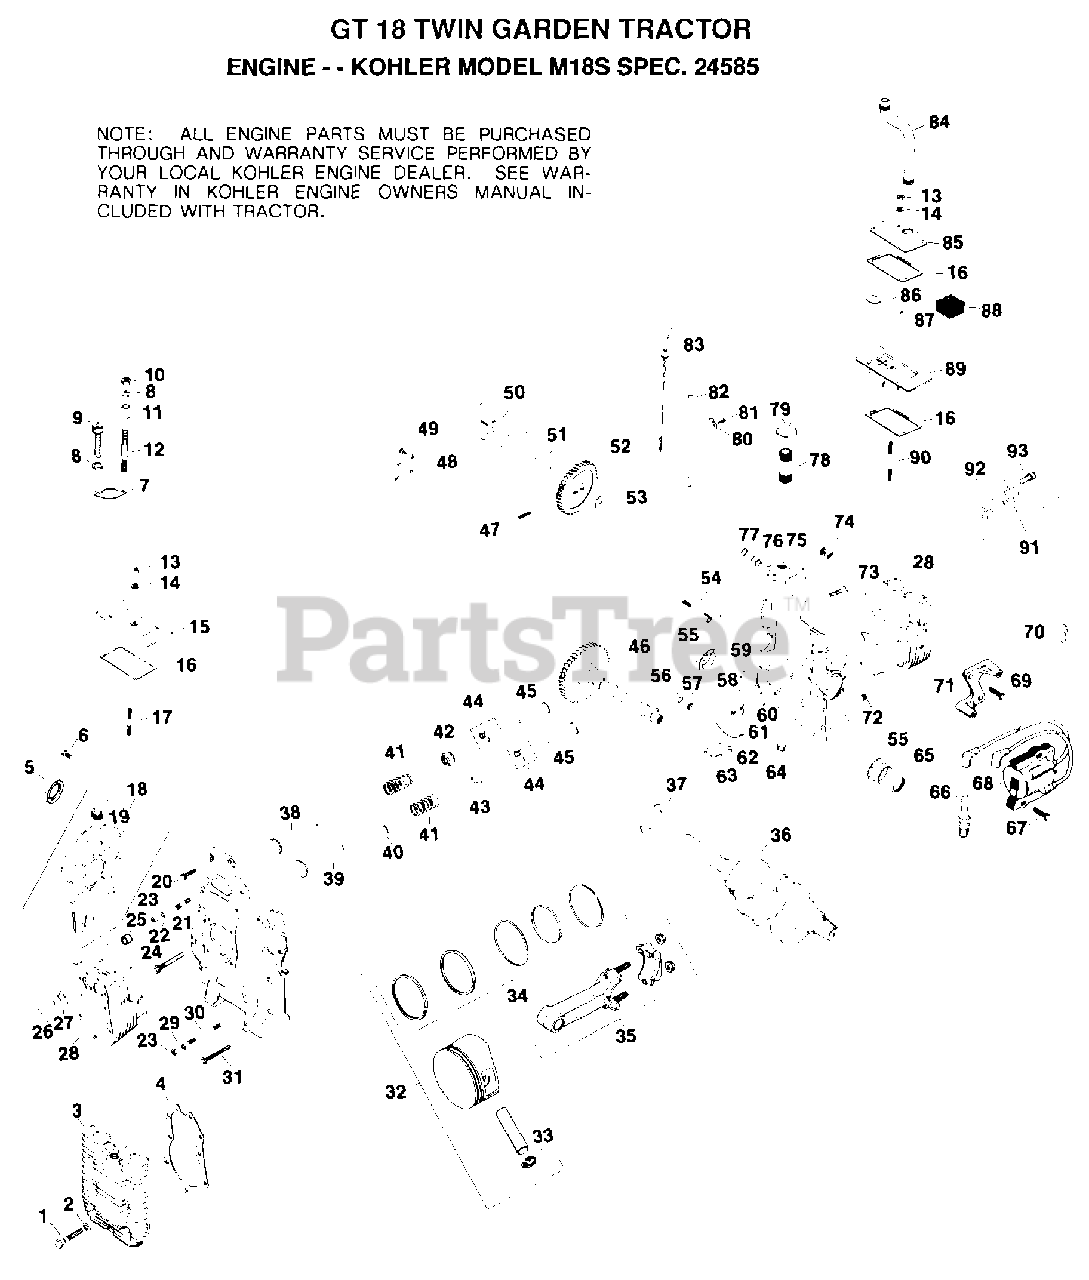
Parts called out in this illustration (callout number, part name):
2	WASHER
3	HEAD, CYLINDER
5	SEAL
6	SCREW
7	GASKET, EXHAUST
8	WASHER
9	SCREW
10	NUT
13	NUT
14	WASHER
15	COVER, #2 CYLINDER VALVE
17	STUD
19	PLUG
23	NUT
25	BUSHING, LOCATING
27	INSERT, VALVE SEAT
28	KIT, CYLINDER BARREL
30	STUD
32	PISTON W/RING SET
32A	PISTON W/RING SET .003"
32B	PISTON W/RING SET .010"
32C	PISTON W/RING SET .020"
32D	PISTON W/RING SET .030"
33	RETAINER, PISTON PIN
34	RING SET, .003"
34A	RING SET, .010"
34B	RING SET, 020"
34C	RING SET, .030"
35	CONNECTING ROD
35A	CONNECT. ROD .010"
37	WASHER, .119/.122 (A.R.)
37A	WASHER, .128/.131
37B	WASHER, .137/.140 (A.R.)
38	VALVE, EXHAUST
39	VALVE, INTAKE
43	RETAINER, INTAKE VALVE
47	PIN, ROLL
48	COVER OIL PUMP
49	SCREW
51	SHAFT OIL PUMP
52	GEAR OIL PUMP
58	TUBE, DIPSTICK
59	PLUG, CUP
61	SCREW
62	CLAMP, SPRING
63	HOUSING, OIL PICKUP
64	PLUG
67	SCREW, 1/4-20 X 1
72	PLUG
74	OIL PRESSURE SWITCH
77	RING, RETAINING
81	SCREW
82	TUBE, OIL LEVEL
83	DIPSTICK, BLADE 11-5/16
84	HOSE, BREATHER
86	VALVE, BREATHER
87	SEAL BREATHER
88	FILTER, BREATHER
89	COVER, #1 LOWER CYLINDER VALVE
90	STUD
92	ADAPTER, OIL FILTER
93	SCREW
